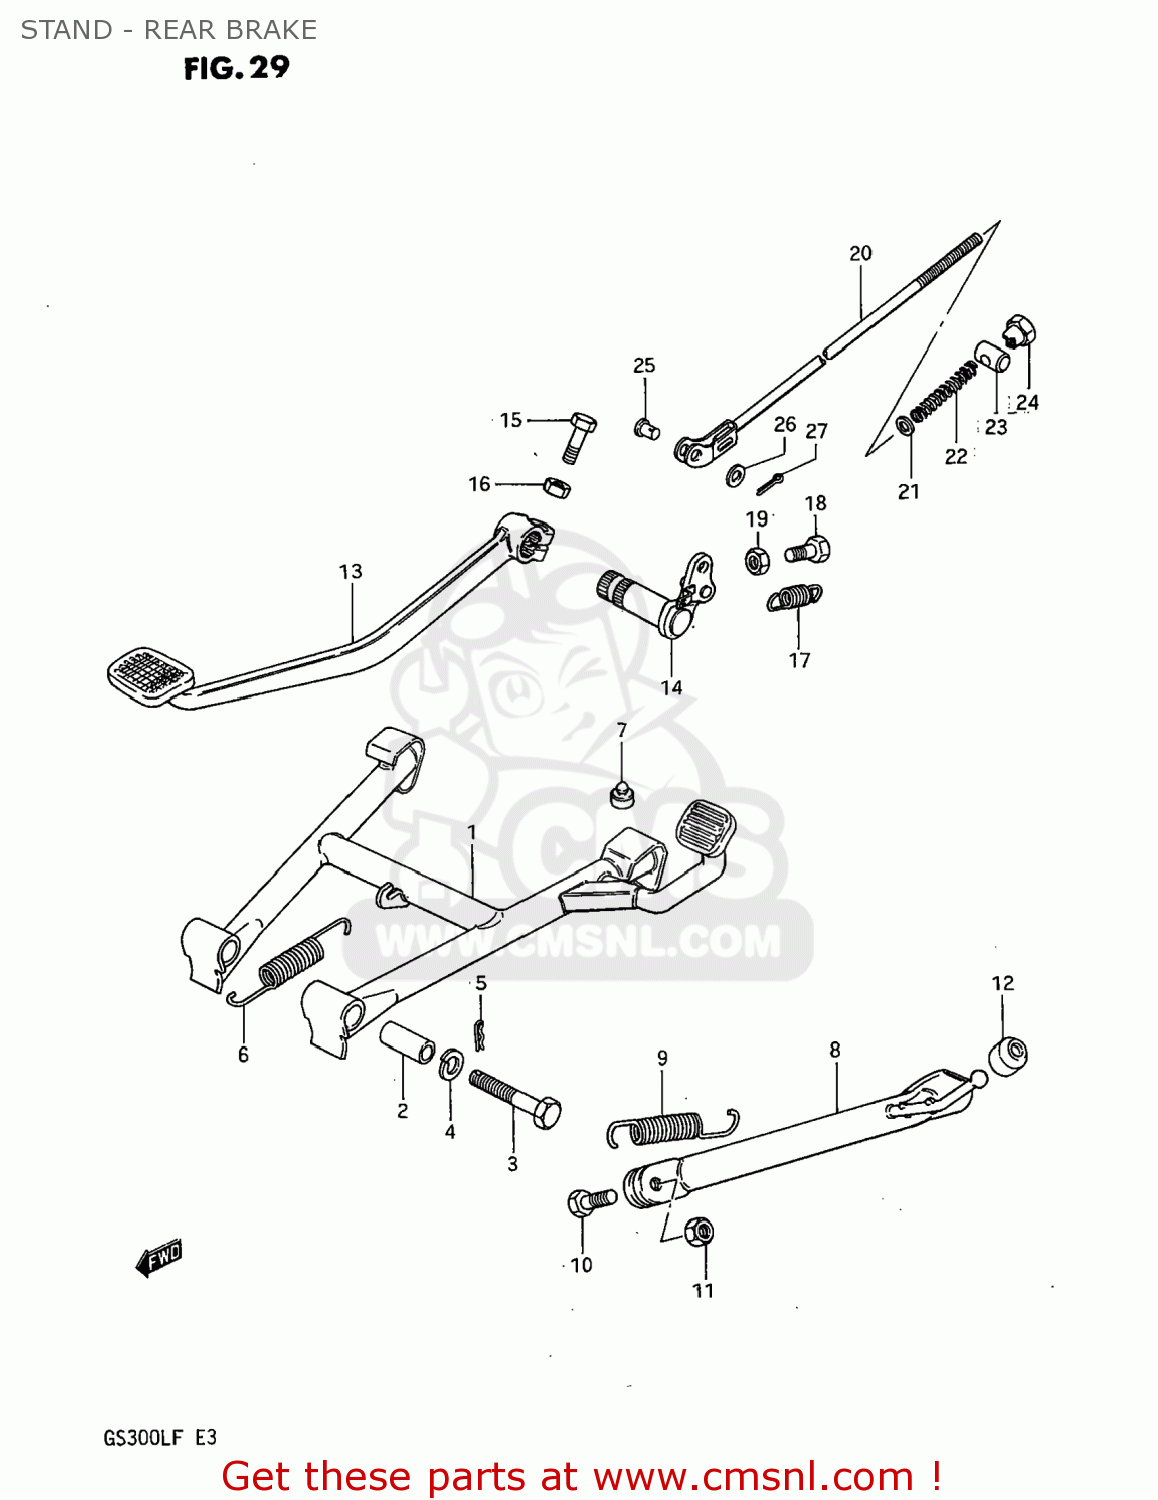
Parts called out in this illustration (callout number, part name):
1	STAND,CENTER
2	SPACER(10X16X38.8)
3	BOLT
4	LOCK WASHER
5	CLIP
6	SPRING
7	CUSHION
8	STAND,SIDE
9	SPRING
10	BOLT(10X30)
11	NUTM10X1.25X8
12	CUSHION
13	PEDAL,BRAKE
14	ARM,BRAKE PEDAL
15	BOLT
16	LOCK WASHER
17	SPRING
18	BOLT
19	NUT
20	ROD ASSY,RR BRAKE
21	WASHER
22	SPRING
23	PIN
24	NUT (6MM)
25	PIN(L:13.5)
26	WASHER
27	PIN 20X20
